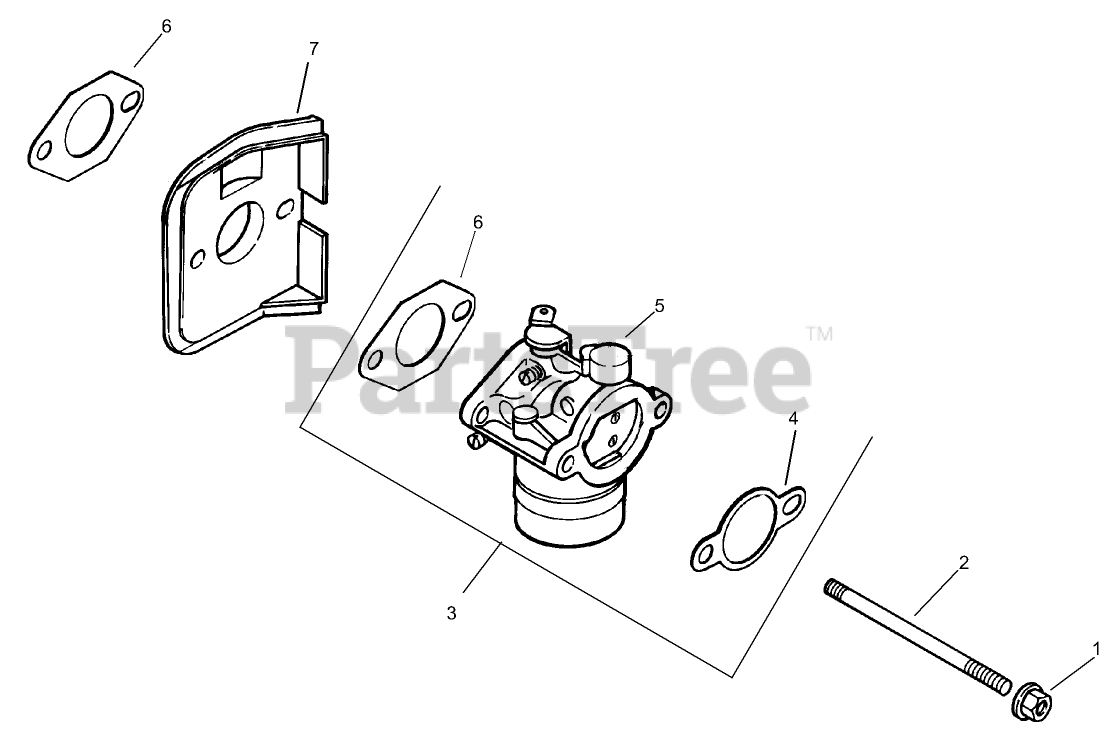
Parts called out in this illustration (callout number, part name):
1	NUT-FLANGE (M6X1.0)
2	Stud (M6x1.0x116)
3	Kit-Carburetor w/Gaskets (Incl. 4-6)
4	Gasket-Base, Air Cleaner
5	Carburetor ASM
6	Gasket-Carburetor
7	Deflector-Heat
8	CLIP-CABLE
